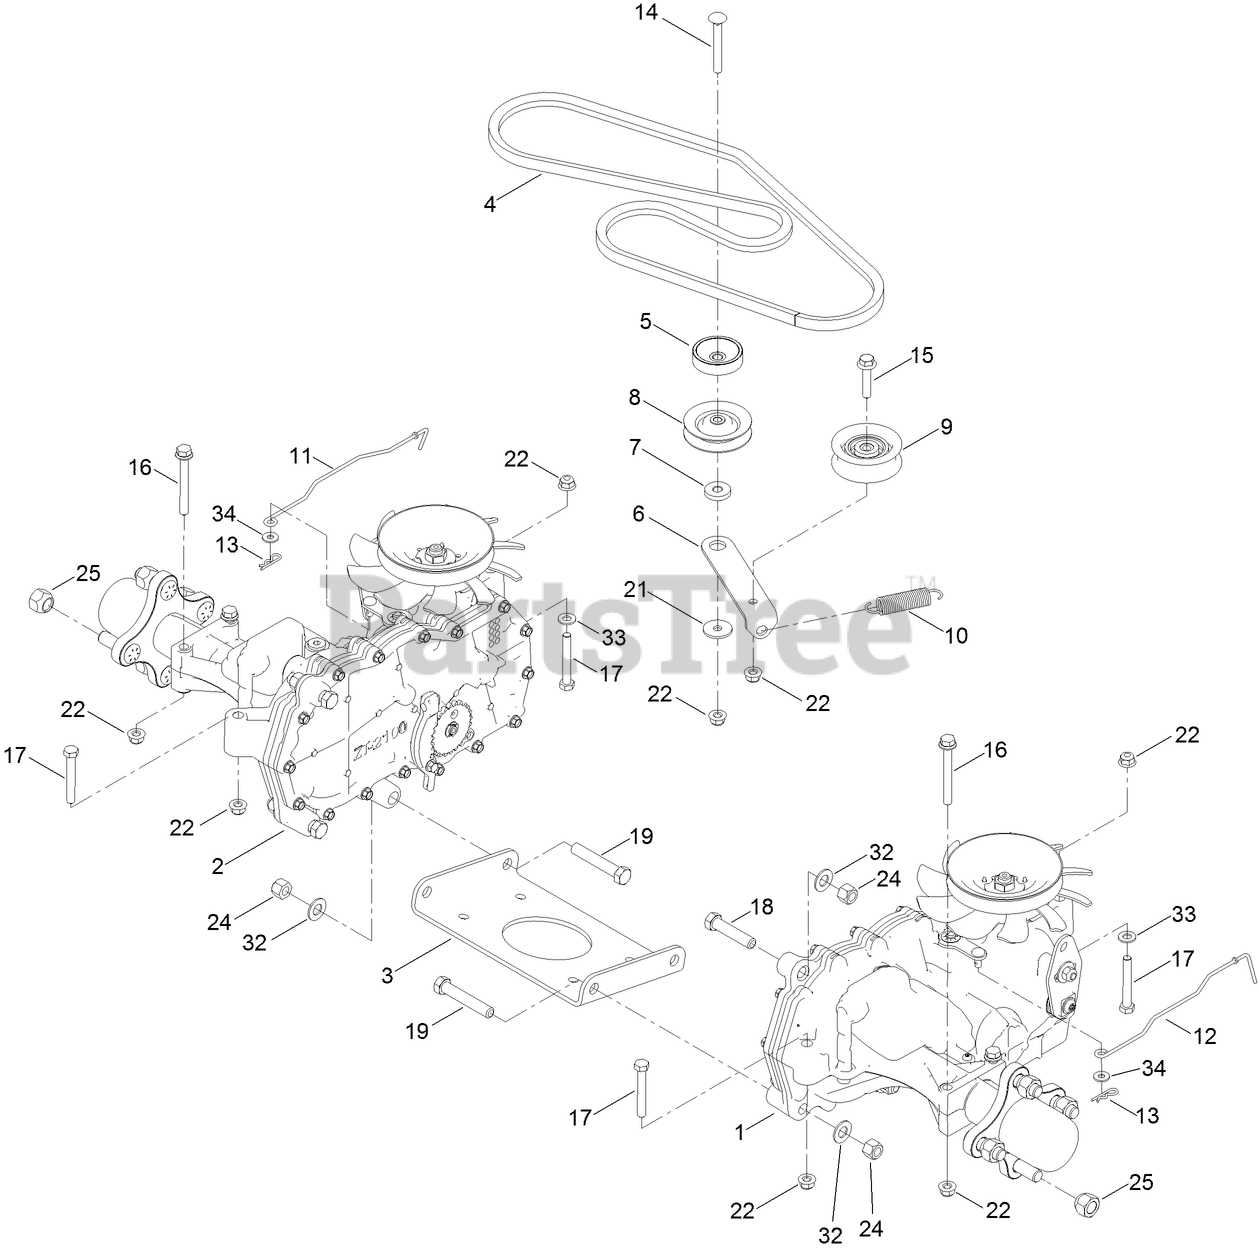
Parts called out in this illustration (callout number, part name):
1	LH HYDRO TRANSAXLE ASM
2	RH HYDRO TRANSAXLE ASM
3	CROSSPLATE-HYDRO
4	V-BELT
5	SPACER
6	ARM-IDLER
7	SPACER-IDLER ARM
9	PULLEY-IDLER, FLAT
10	SPRING-PEDAL, RETURN
11	ROD-BYPASS, RH
12	ROD-BYPASS, LH
14	SCREW-CARR
15	SCREW-HHF
16	SCREW-HHF
17	SCREW-HH
18	SCREW-HH
19	SCREW-HH
21	WASHER-PIVOT
22	NUT-HF, NI
24	NUT-LOCK, NI
25	NUT-LUG
32	WASHER-FLAT
33	WASHER-PLAIN
34	WASHER
